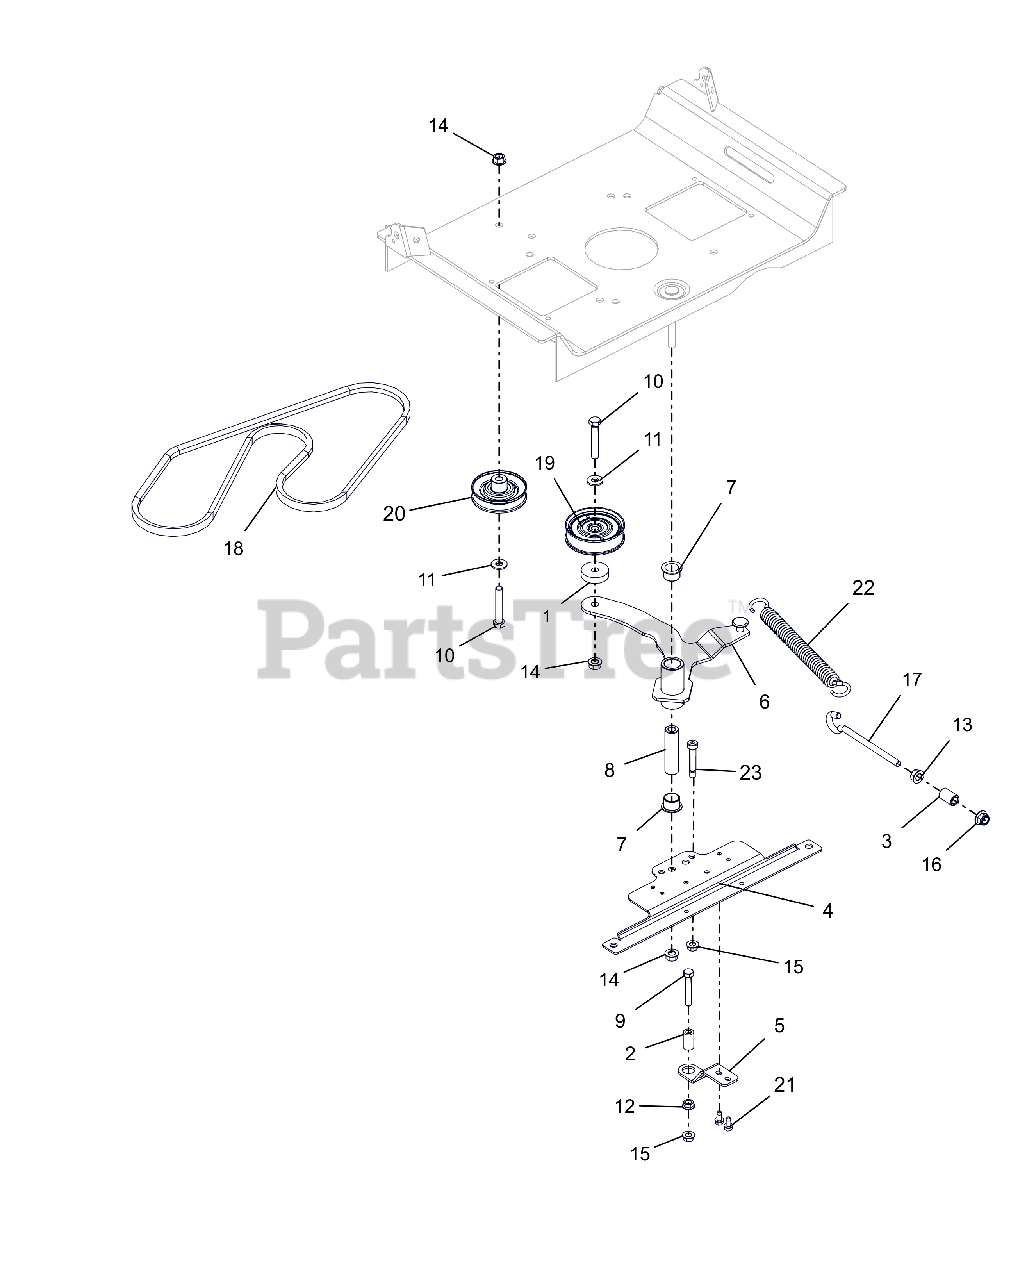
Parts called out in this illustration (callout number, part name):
1	SPACER, .39 X 1.50 X .380
2	SPACER, RUBBER 5/16 IDX1.0 LG
3	SPACER, .375X.625X.970 (PM)
4	BRKT, DRIVE IDLER MOUNTING
5	BRKT, CLUTCH STOP (XL)
6	WLDMT,GRD DRIVE IDLER ARM-LGR
7	BSHG-FLG 0.75X0.875X.625X1.125
8	BUSHING, SLEEVE .38X.750X2.78
9	@BLT-HEX .31-18X2.00 GR5 YWZC
10	@BLT-HEX .38-16X2.25 GR5 YWZC
11	@WSHR-FL-STL.38X.875X.083 YWZC
12	@NUT-SPNLK-FLG .312-18 YWZC
13	@NUT-SPNLK-FLG .375-16 YWZC
14	@NUT-LK-TOP-FLG .38-16 YWZC
15	@NUT-LK-TOP-FLG .31-18 YWZC
16	@NUT-LK-NYL-FLG .38-16 YWZC
17	BOLT,.38-16 X 4.25-.62 DIA EYE
18	V-BELT, A-RAW EDGE
19	IDLER, FLAT - 3.05" X .75"
20	IDLER, V-3.000 OD
21	SCR-TAP .25-20X.50 HWH TR YWZ
22	SPRING, EXTENSION
23	BLT-SHLDR .38X1.5X.31-18 SLT Y
